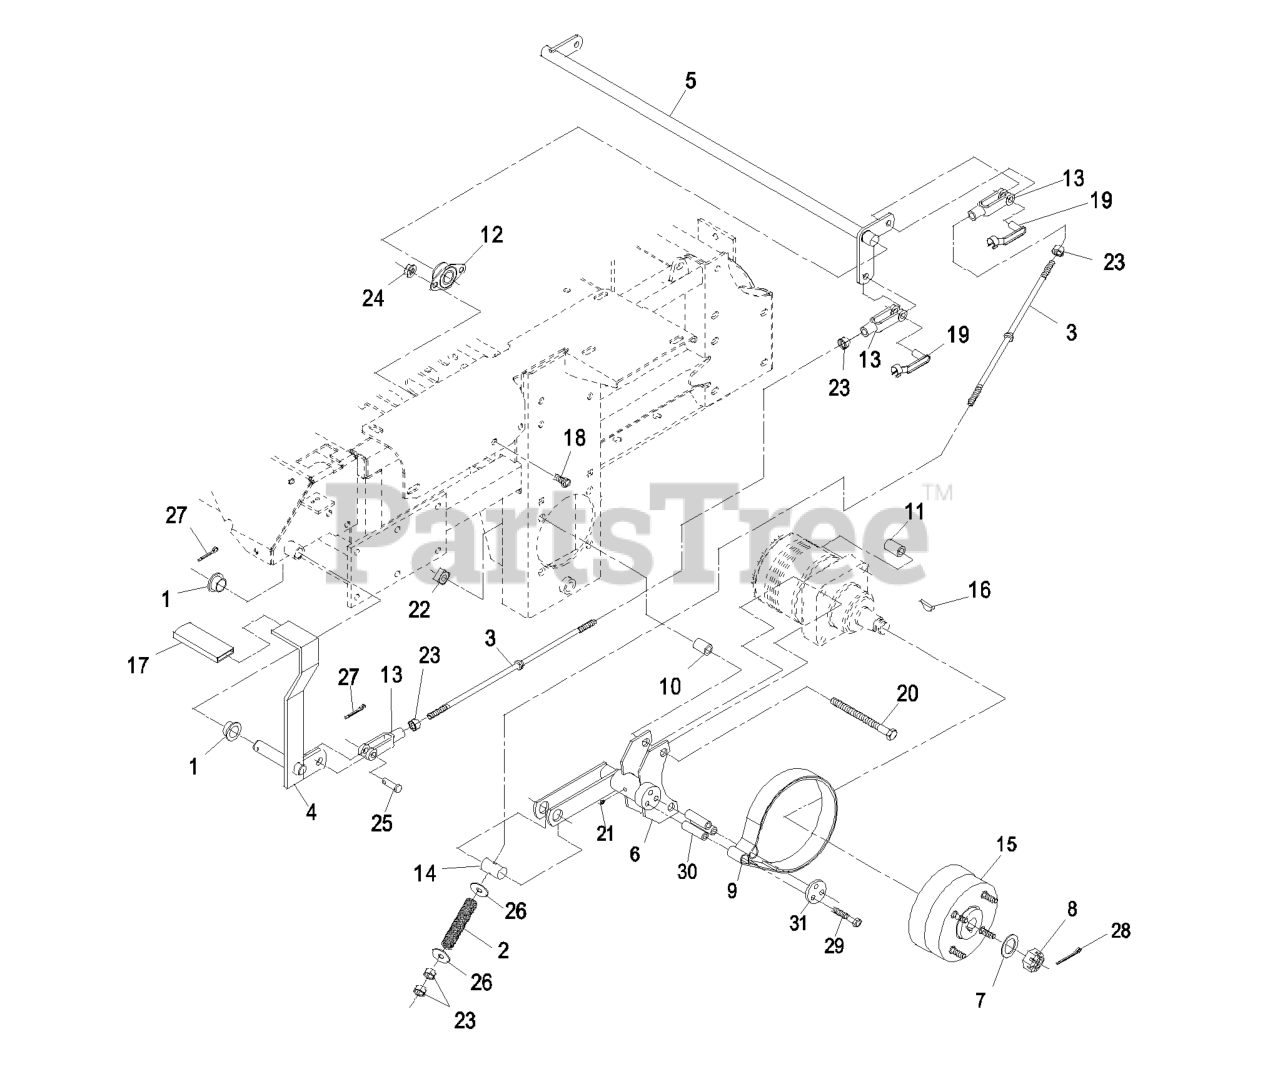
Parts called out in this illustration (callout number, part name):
1	BEARING-CONTROL
2	SPRING-BRAKE
3	ROD-BRAKE
4	BRAKE LEVER ASM
5	SHAFT-BRAKE
6	BRACKET-BRAKE
7	WASHER-SPACER
9	BAND,BRAKE
10	SPACER-WHEEL, SHORT
11	SPACER-WHEEL, LONG
12	BEARING-FLANGE, SIDE
13	YOKE-LINKAGE, BRAKE
14	PIN-TRUNION
15	WHEEL HUB ASM
16	KEY-WOODRUFF
17	GRIP-LEVER
18	SCREW-HH
19	PIN-SPRING, CLEVIS
20	SCREW-HH
21	FITTING-GREASE
22	NUT-SQUARE, SPECIAL
23	NUT-HEX
24	NUT-HHF, WHIZ
25	PIN-CLEVIS
26	WASHER-FLAT
27	PIN-COTTER
28	PIN-COTTER
29	SCREW-HH
31	RETAINER-BAND, BRAKE
